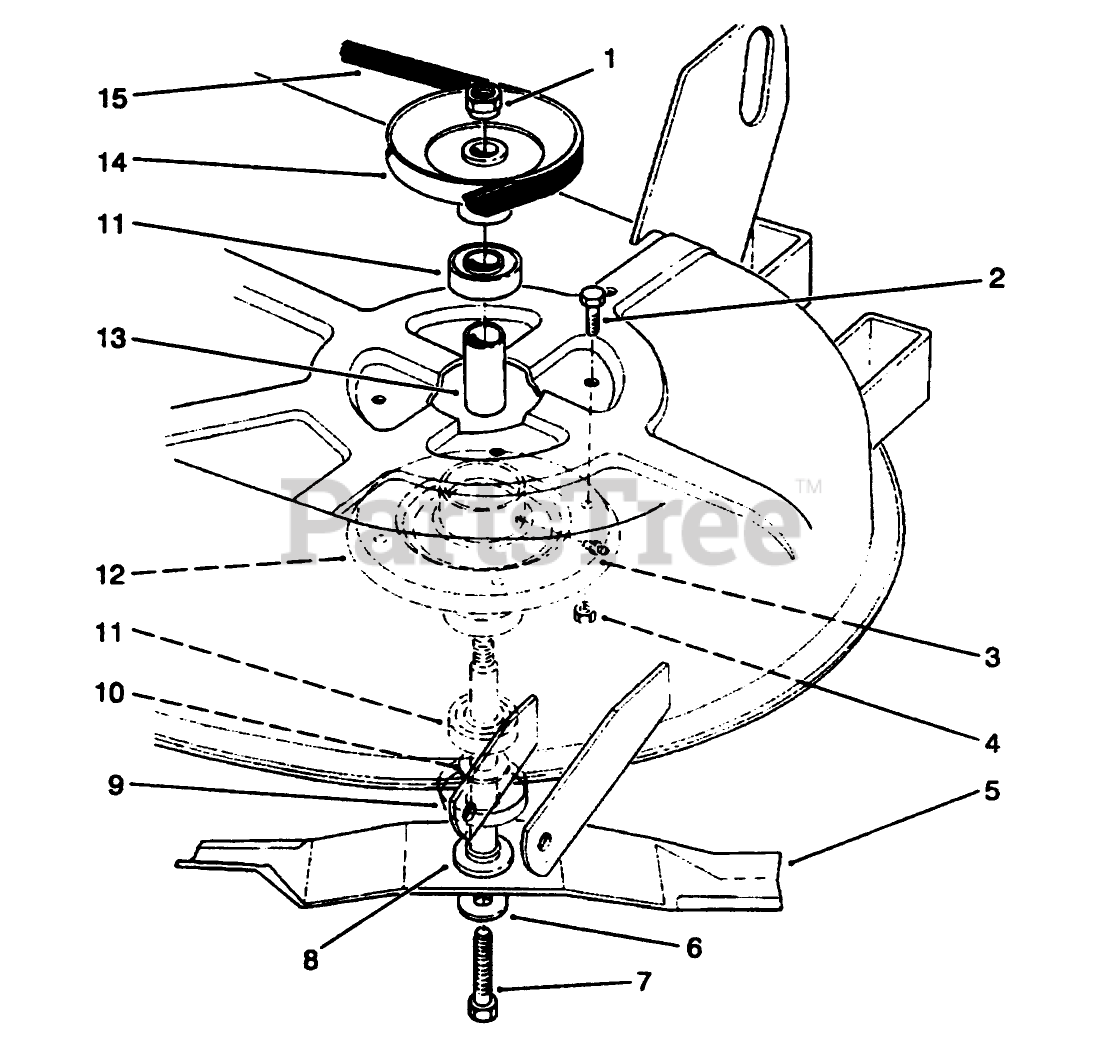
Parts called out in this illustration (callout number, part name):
1	Nut-Hex
2	SCREW-HH
3	ZERK FITTING
4	NUT-LOCK, NI
5	BLADE KIT
6	WASHER-BELLEVILLE
7	SCREW-HH
8	SHAFT-SPINDLE
9	SHIELD-BEARING
10	SPACER-HARDNED
11	BEARING-BALL
12	Housing-Spindle
13	SPACER
14	Pulley-Spindle
15	V-BELT
